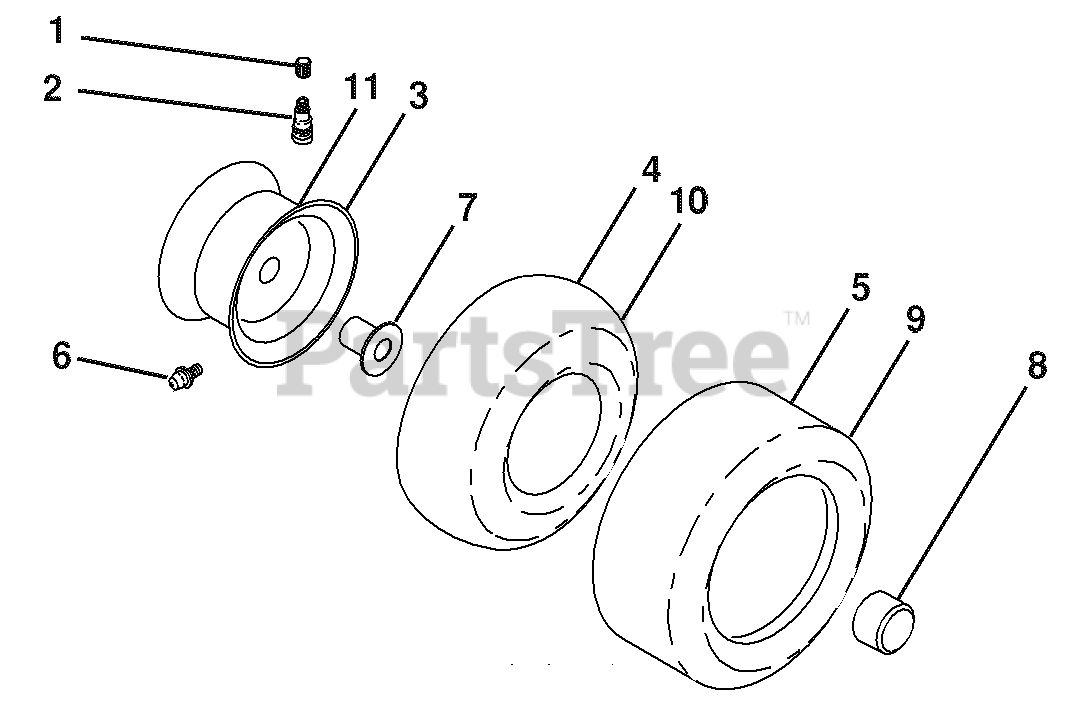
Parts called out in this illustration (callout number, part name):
1	Cap Valve Tire
2	Stem Valve
3	Tire F T 15 x 6 0 - 6 Service
4	Tube Front
5	Rim Asm 6" front Service
6	Fitting Grease
7	Bearing Flange
8	Cap Axle Blk 1 50 x 1 00
9	Tire R T 18 x 9.5-8 Service
10	Tube Rear
11	Rim Asm 8" rear Service
